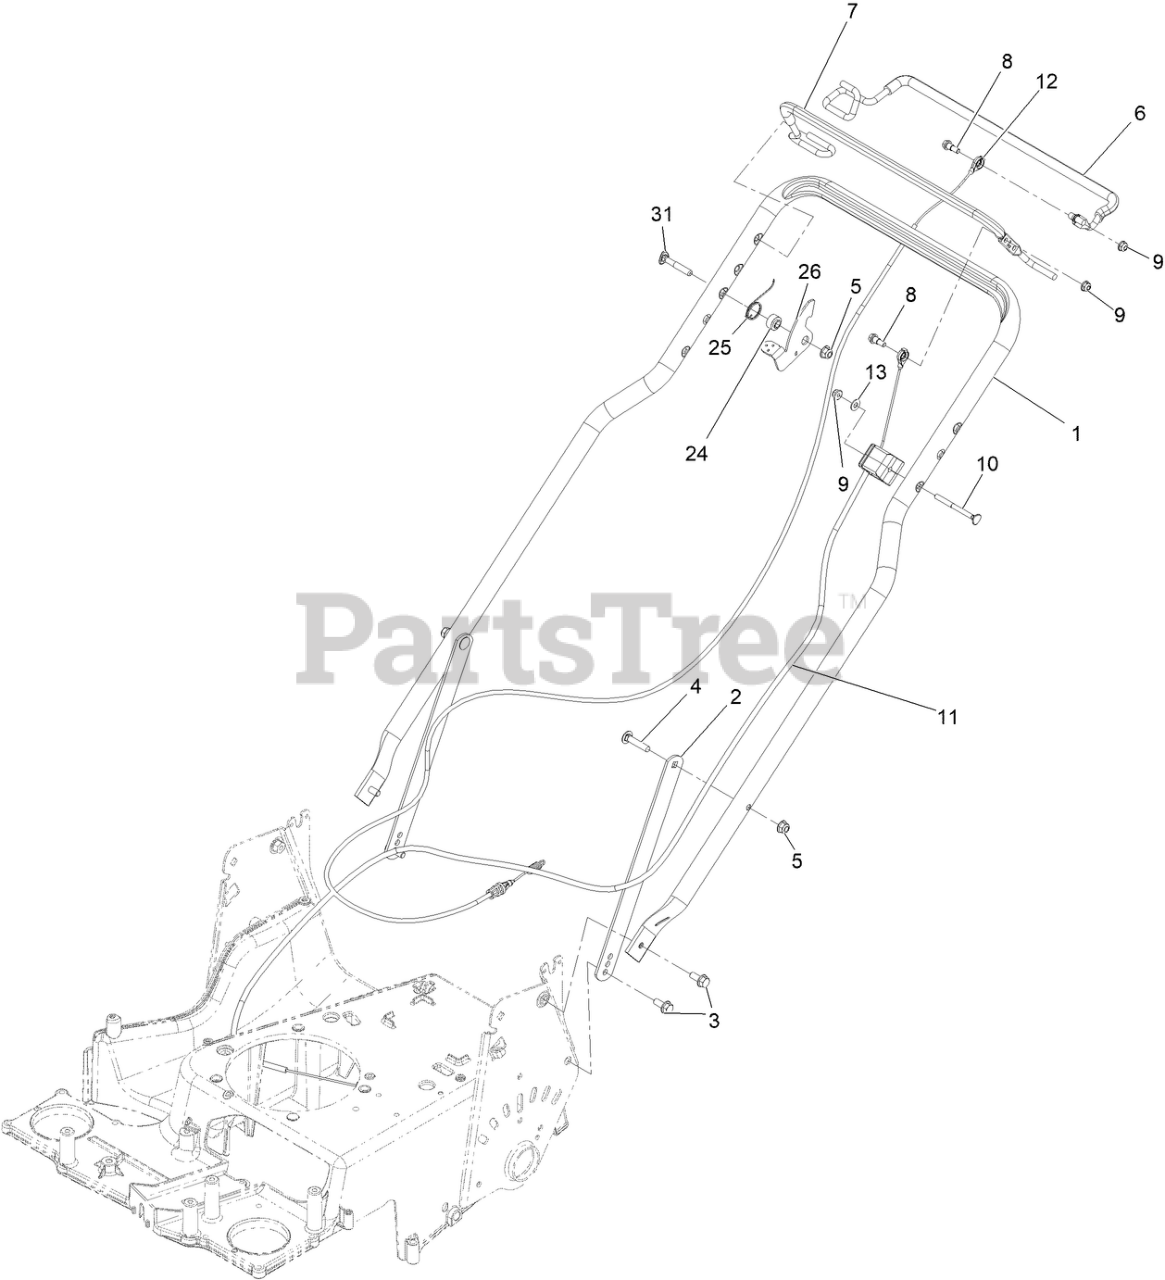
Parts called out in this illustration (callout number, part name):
2	SUPPORT-HANDLE
3	SCREW-HHF
4	BOLT-CARR
5	NUT-HF, NI
6	BAIL-TRACTION, COATED
7	BAIL-BBC, COATED
8	BOLT-SHOULDER
10	Screw-Handle
11	CABLE-BBC
12	CABLE-TRACTION
13	Washer-Flat
24	BUSHING-STEPPED
25	SPRING-LEVER, BBC
26	LEVER-BBC
